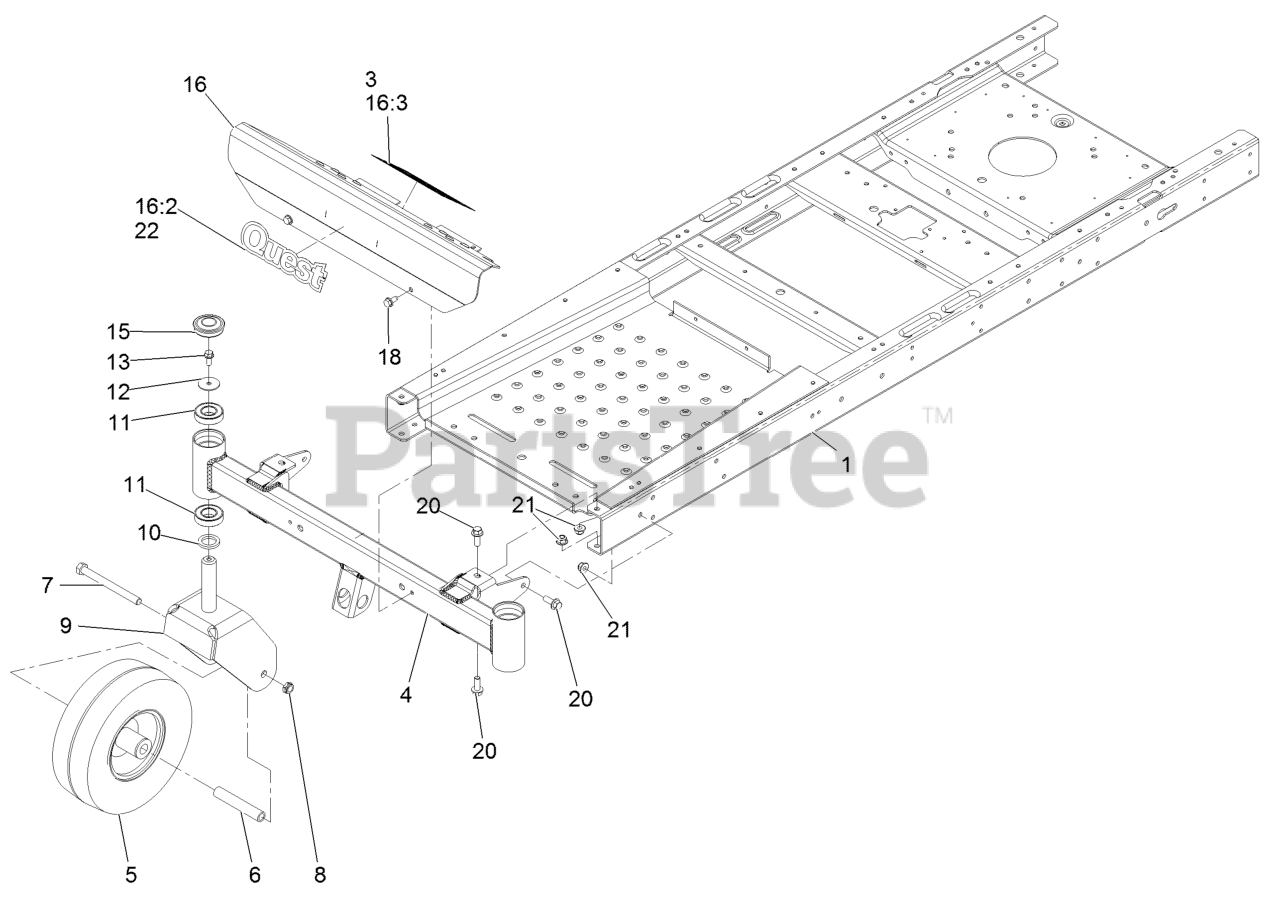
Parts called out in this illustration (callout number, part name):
1	FRAME ASM
3	DECAL-DANGER
4	AXLE-FRONT, NARROW
5	CASTER WHEEL ASM
6	BUSHING-SPANNER
7	SCREW-HH
8	NUT-HEX
9	FORK-CASTER
10	WASHER-THRUST
11	BEARING-BALL
12	WASHER-FLAT
13	SCREW-HHF
15	CAP-GREASE
16	FOOTREST ASM
16:3	DECAL-DANGER
18	Screw-HWH 5/16-18 X 3/4 Tf
20	SCREW-HHF 3/8-16 X 1
21	NUT-HF, NI
